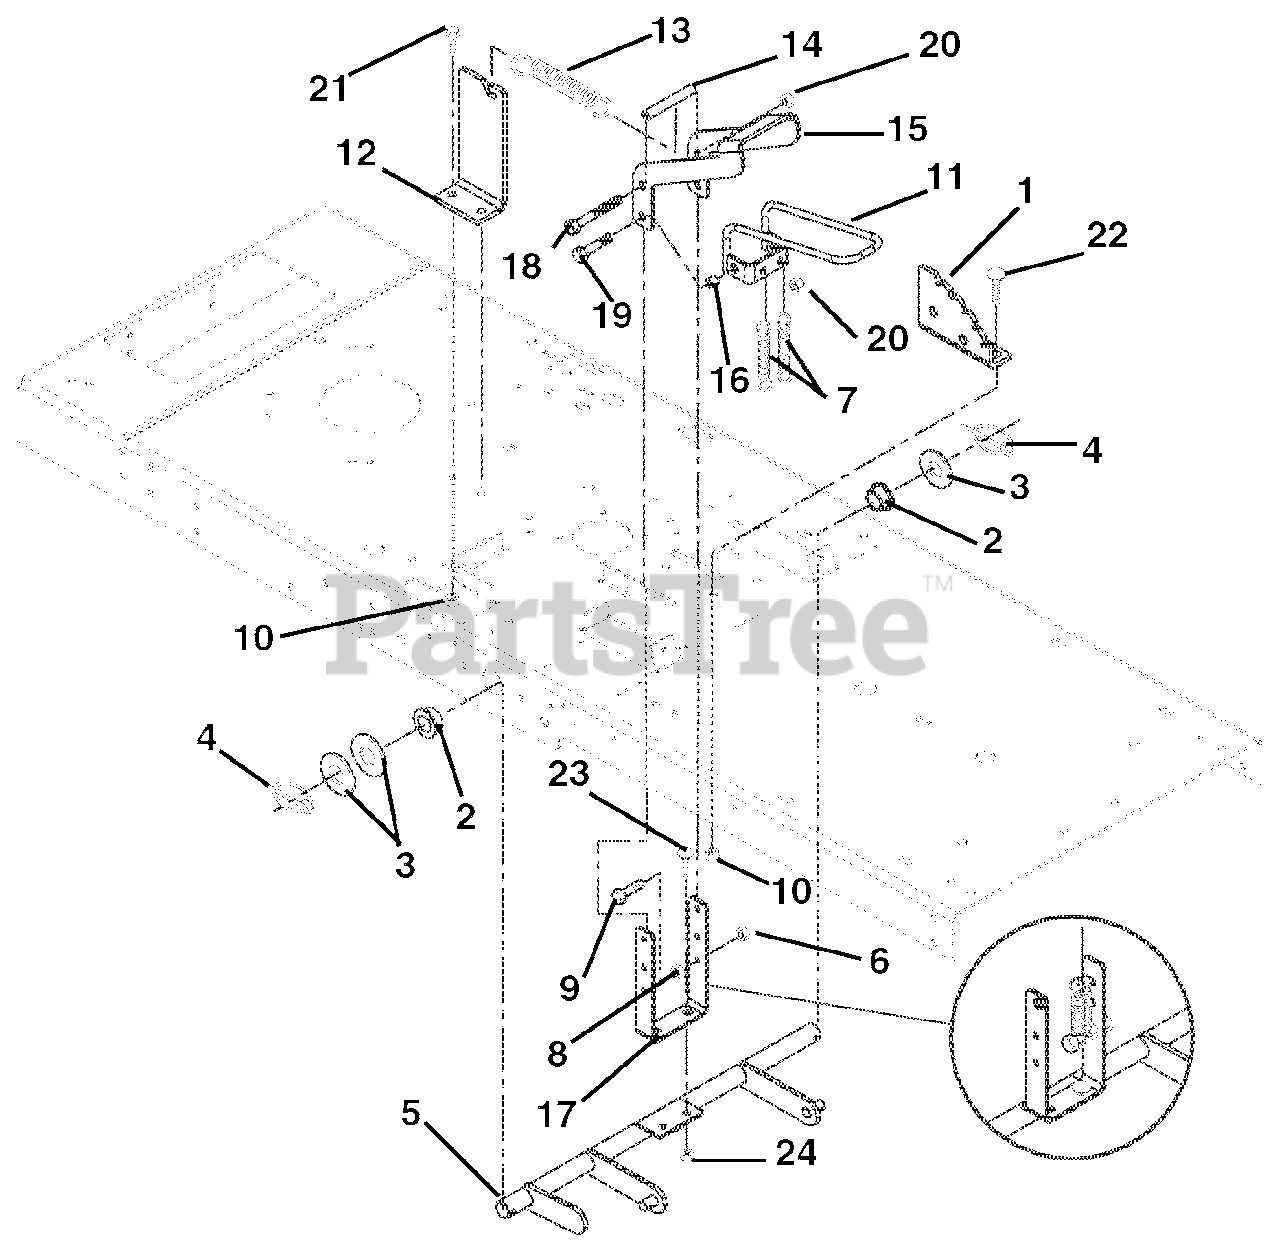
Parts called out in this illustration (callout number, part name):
1	Detent Plate
2	Bushing-Flange 1.020 x 1.385 x .75 x 1.75
3	Washer-Flat-Steel 1.062 x 2.000 x .134
4	Pin-Klik .25 x 1.75
5	Lift Lever Weldment
6	Nut-Locking-Center .25-20
7	Spring-Tension .092 x .69 x 1.75
8	Nut-Hex .25-20
9	Bolt-Hex .25-20 x 2.00 Grade 5
10	Nut-Locking-Top-Flange .38-16
11	Weldment-Release
12	Bracket-Lift
13	Spring-Tension
14	Spacer .328 x .462 x 3.14
15	Handle-Deck Lift
16	Spacer .328 x .462 x .41
17	Bracket-Handle
18	Bolt-Hex .312-18 x 4.50 Grade 5
19	Bolt-Hex .312-18 x 1.25 Grade 5
20	Nut-Locking-Nylon .312-18
21	Bolt-Screw Hex Flanged Whiz Lock Head .38-16 x .75
22	Bolt-Round Head Square Neck .375-16 x .75 Grade 5
23	Bolt-Round Head Square Neck .375-16 x 1.00 Grade 5
24	Nut-Locking-Top Flange .38-16
